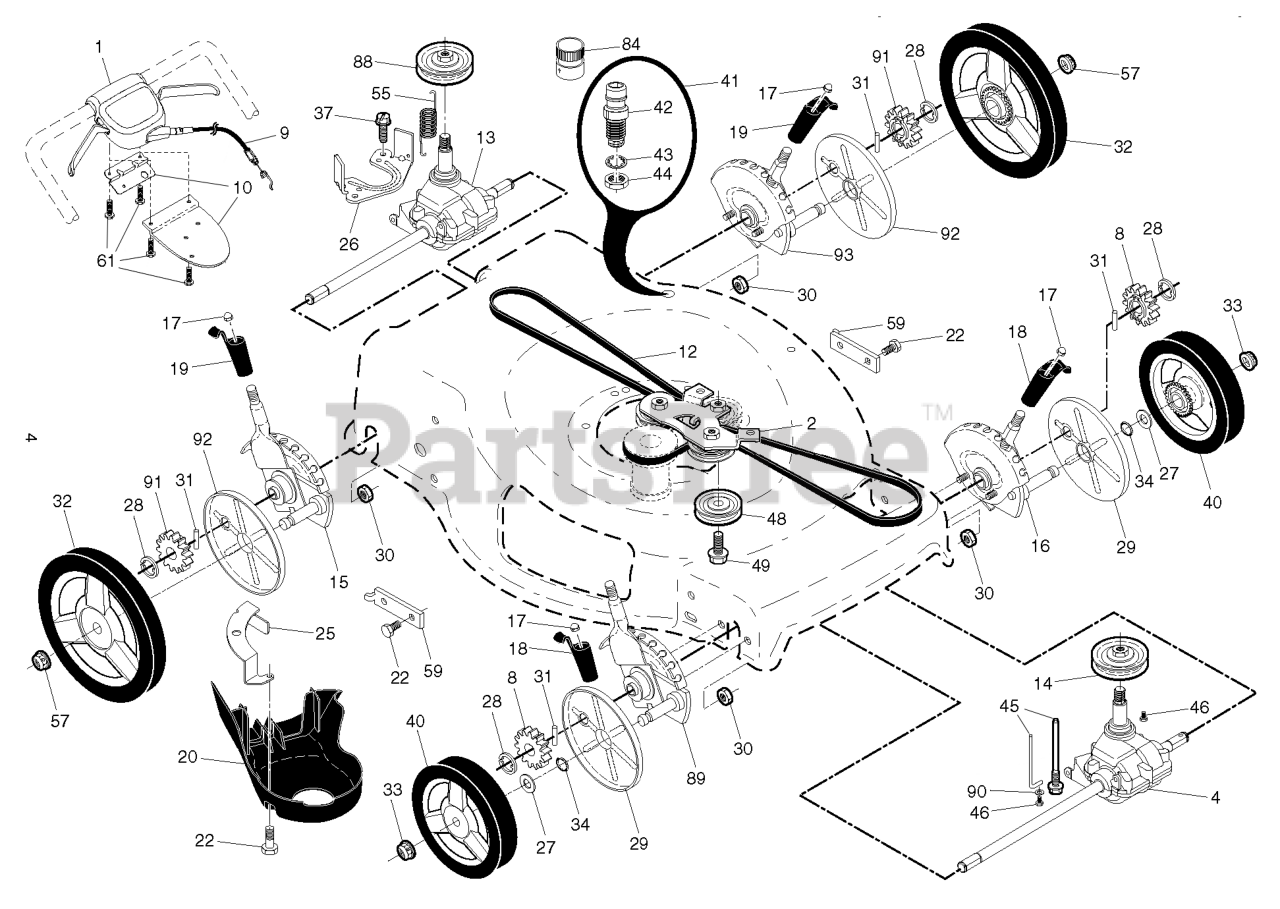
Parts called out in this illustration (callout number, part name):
1	CONTROL.AWD.DT.BS
2	BRACKET.ASM.AWD.BZP.BLACK
4	TRANSMISSION.22+.AWD.FRT
8	PINIION.14.TOOTH.RGD
9	CABLE.DRIVE.RWD.WALK.
10	BRACKET DUAL TRIGGER CONTROL
10	BRACKET.DRIVE.CONTR.GEN2.BLACK
12	BELT V3L 64.10 CLUTCHING COVER
12	BELT.DRIVE.AWD.13 ZINC DUSTED
13	TRANMISSION.ASM.22+AWD.REAR
13	TRANSMISSION.22+AWD.WALK.MOWER
14	PULLEY AWD/RGD, SCREW-ON AWD/R
14	PULLEY.DRIVE.SM.AWD/RWD
15	ADJUSTER.ASM.HW.RR.AWD
16	ADJUSTER.ASM.FG/AWD.LF/QP.BZIN
16	KIT.ADJ.22+QP.LF.BLACK.ZINC
17	NUT.PUSH.156
18	KNOB.ADJUSTER.LW.BLK
19	KNOB.ADJUSTER.REAR.BLACK
20	COVER.REAR.DRIVE.22+2013
22	BOLT.5/16HEX.WHS.HD
25	BRACKET.DRIVE.COVER.RGD.BZP
26	BRACKET.TRAN.BELTKEEPER.22+RGD
27	WASHER FLUT
28	E-RING 7/16 RE
29	COVER.DUST.WHEEL.INNER.WALK
30	NUT.FLANGE.1-4-20-SERR
31	PAWL, DRIVE
32	WHEEL.11.H3SP.AWD.LC.460.BB2
33	NUT.HEX.FLANGE.3/8-16.LO(3 2)
34	O-RING..070X.487.NEOPRENE
40	WHEEL.8".AWD.3SP.EXT.DR.GREY
41	KIT.WASH-OUT.PORT.ZINC.WALK
42	WASHOUT.PORT.ZINC.RGD.22+
43	WASHER.LOCK.INTERNAL.TOOTH
44	LOCKNUT.HEX.WITH.O-RING
45	BRACKET.AWD.FRONT.BELT.KEEPER
45	SCREW.HI-LO.5/16-14 X 4.10
46	SCREW.HI-LO. 5/16 X 1.00
48	PULLEY.ASM.22+ AWD
55	SPRING.RETURN.AUTO.
57	NUT.HEX.FLANGE.3/8-16.LO(3 2)
57	NUT.HEX.FLANGE.3/8-16.LOCKNUT
59	BRACKET.SUPPORT.22+RWGD.BZP
61	SCREW, PHILLIPS HEAD 10 X 5/8
84	COUPLING.QUICK CONNECT
88	PULLEY.DRIVE.SM.AWD/RWD
88	PULLEY
89	ADJUSTER.ASM.HW.AWD.LR
89	ADJUSTER.ASM.FG/AWD.RF.QP.BZIN
90	WASHER 5/16 FLAT
91	PINION.16.TEETH.HW.AWD.REAR
92	COVER.DUST.WHEEL.HW.AWD.REAR
93	KIT.ADJ.22+QP.LR.HW.BLK.ZINC
93	ADJUSTER.ASM.HW.AWD.LR
